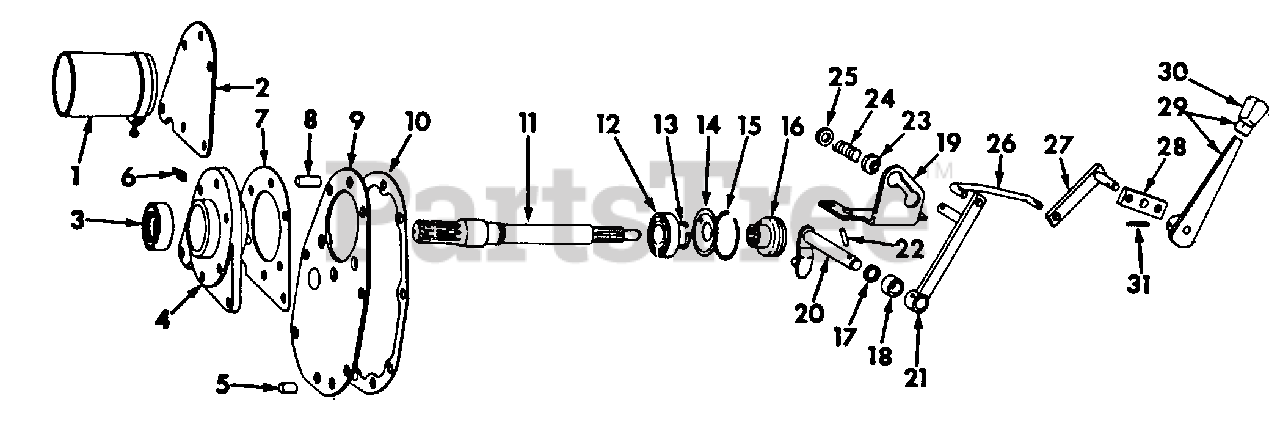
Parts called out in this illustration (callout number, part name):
1	Guard Assy, PTO Shaft
2	Cover, Transmission Case Rear Cover Opening
3	Seal, PTO Shaft Oil
4	Retainer, PTO Shaft Oil Seal & Brg
5	Pin, Cover Lower Dowel
6	Fitting, 3/16 X 65 Deg Drive Type Lube
7	Gasket, Rear Cover Opening
8	Pin, Cover Upper Dowel
9	Plate Assy, Transmission Rear Cover
10	Gasket, Rear Cover
12	Bearing, PTO Shaft Ball
13	Ring, PTO Shaft Brg Snap
15	Ring, PTO Shaft Brg Snap
16	Clutch, PTO Shifter
17	Seal, PTO Shifter Shaft
18	Spacer, PTO Shifter Lever
19	Guide, PTO Shifter Arm
20	Lever Assy, PTO Shifter
21	Arm Assy, PTO Shifter
22	Pin, 1/4 X 1 Hv Coiled Spring
23	Washer, PTO Shifter Arm Ball
24	Spring, PTO Shifter Arm
25	Washer, 11/32 X 11/16 X .065
26	Rod, PTO Control Lever Link
27	Lever Assy, PTO Control
28	Bar, PTO Control Lever Brg
29	Handle Assy, Pto Control
30	Knob, PTO Shifter Handle
31	Pin, 1/8 X 7/8 Hv Coiled Spring
